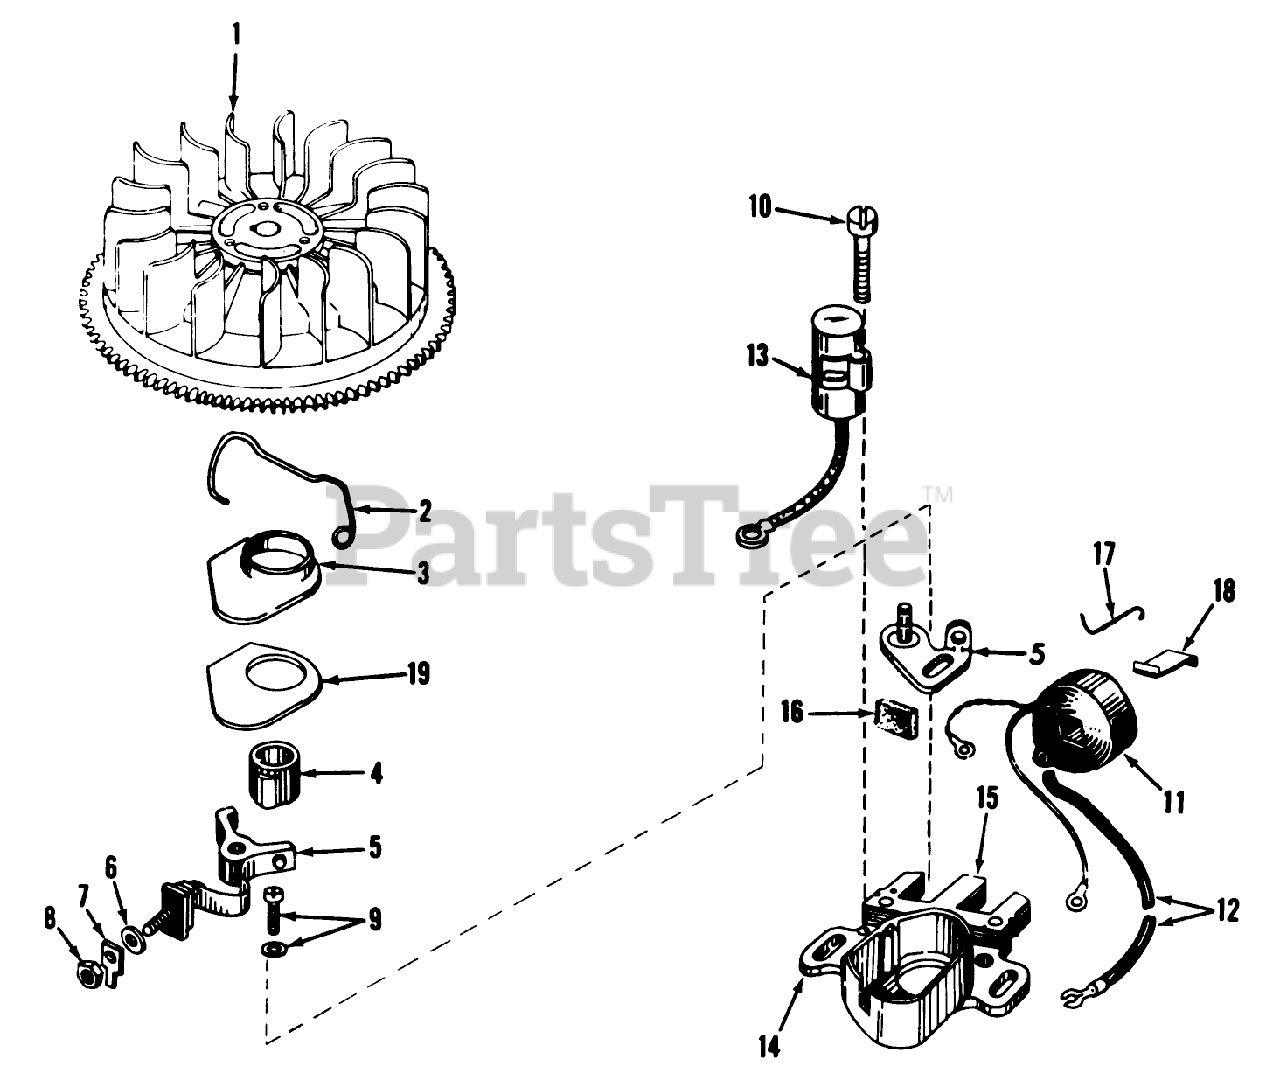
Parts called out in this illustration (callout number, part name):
1	Flywheel
2	Spring Breaker Box
3	Cover, Dust
4	Cam-Breaker
5	Breaker Assy.
6	Washer
7	Terminal
8	DECAL
9	Breaker Screw
10	Condenser Screw
11	Coil Assy. (Incl. No. 12)
12	Wire, Lead
13	Condenser
14	Core Plate
15	Stator Assy., (Incl. Nos. 2, 3, 5 thru 14 16 thru 19)
16	Felt,Cam Wiper
17	Clip, Coil
18	Spring Coil Wedge
19	Gasket Dust
